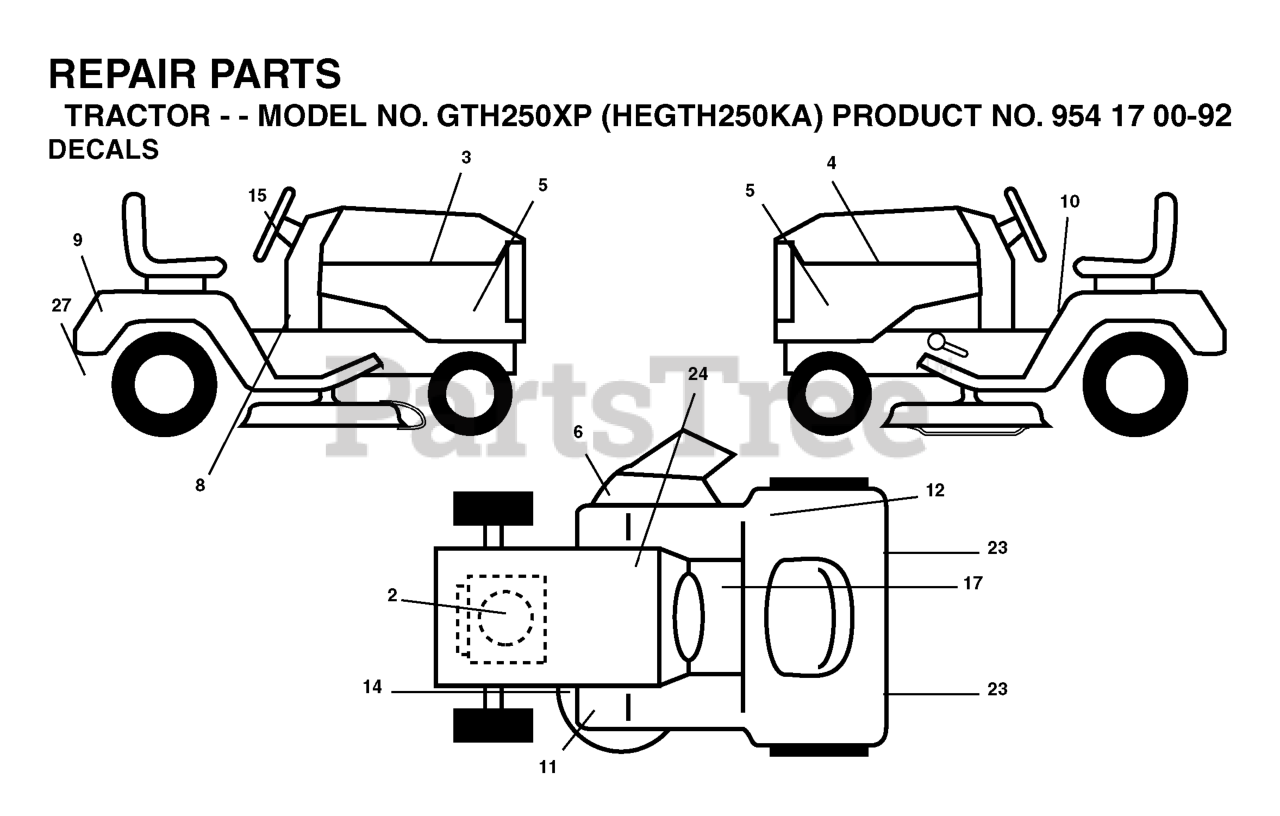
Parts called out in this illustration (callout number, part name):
3	HOOD DECAL RH
4	HOOD DECAL LH
6	DECAL.INTERNATIONL.CUTFINGER
8	Decal, Dash
9	DECAL, FENDER
10	DECAL READ OWNER'S MAN SYMS
11	Decal, Foot Rest
12	DECAL.FENDER
14	DECAL V-BELT SCHEMATIC
15	DECAL.WHEEL.STEERING.HUSQ.PERM
17	DECAL PARK BRAKE
23	REFLECTOR-TAIL YT
24	DECAL BTRY SYMBOLS
27	DECAL.BYPASS.FENDER.CRD.LT.YT
